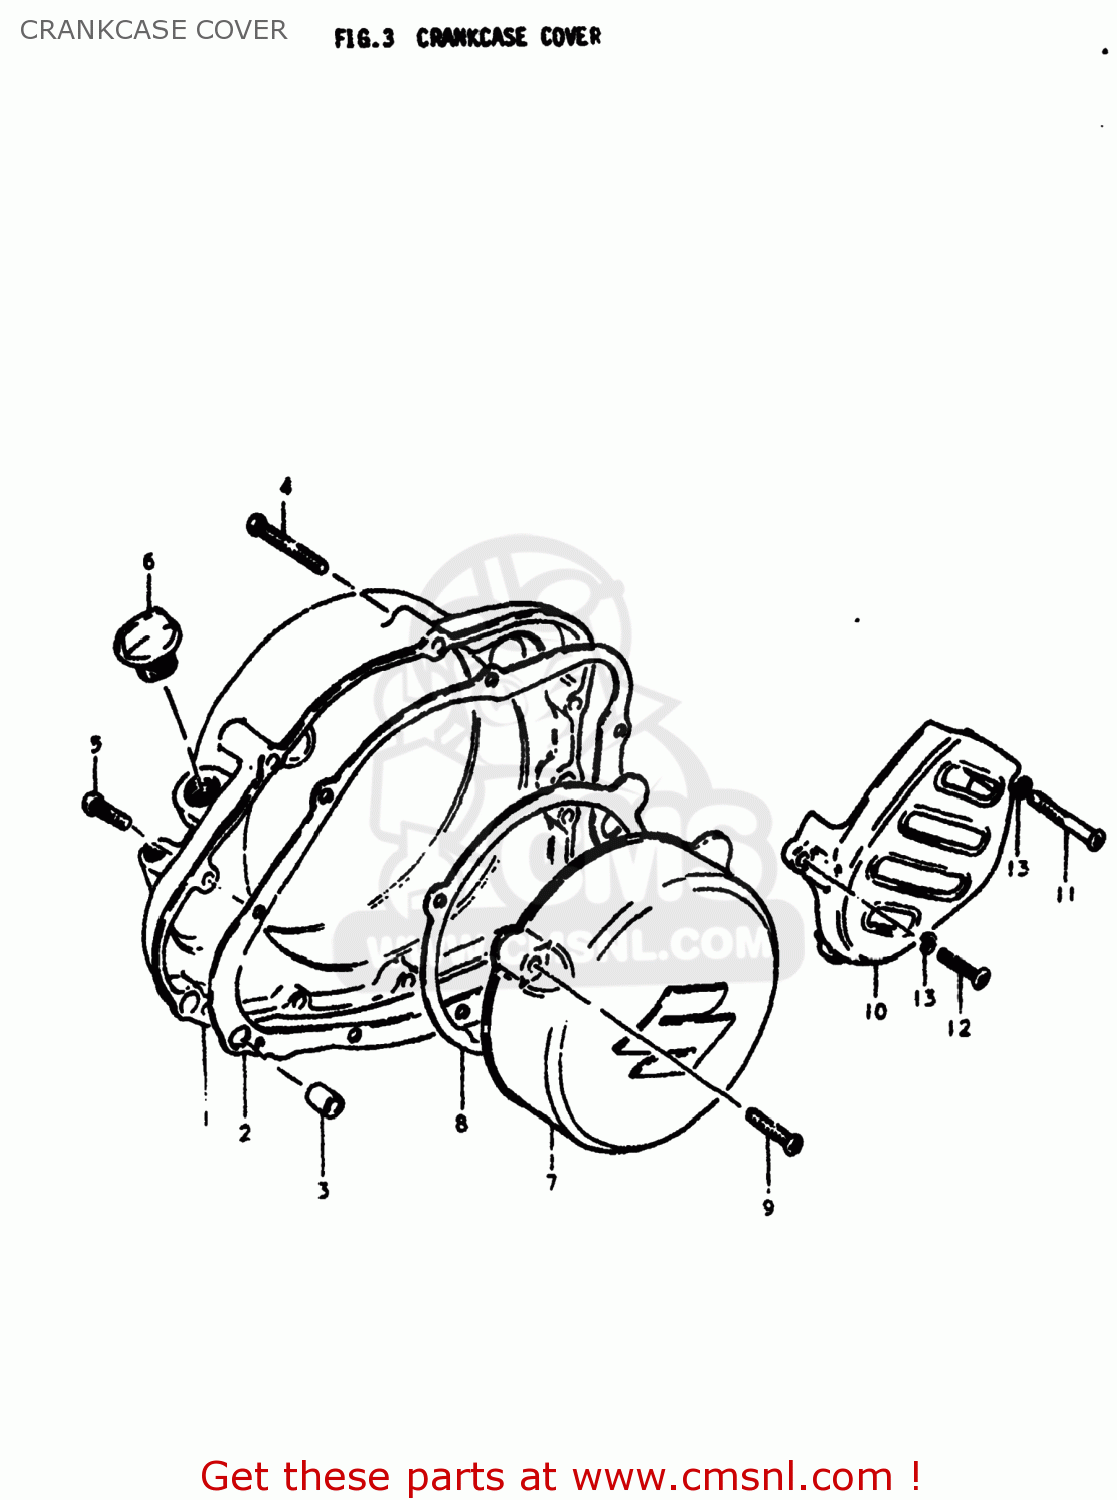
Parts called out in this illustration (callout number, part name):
1	COVER,CLUTCH
2	GASKET,CLUTCH COVER (MCA)
3	PIN
4	SCREW (6X45)
5	SCREW
6	PLUG,OIL FILTER
7	COVER,MAGNETO
8	GASKET,MAGNETO COVER (NAS)
9	SCREW
10	COVER,ENGINE SPROCKET
11	SCREW
12	SCREW
13	LOCK WASHER
